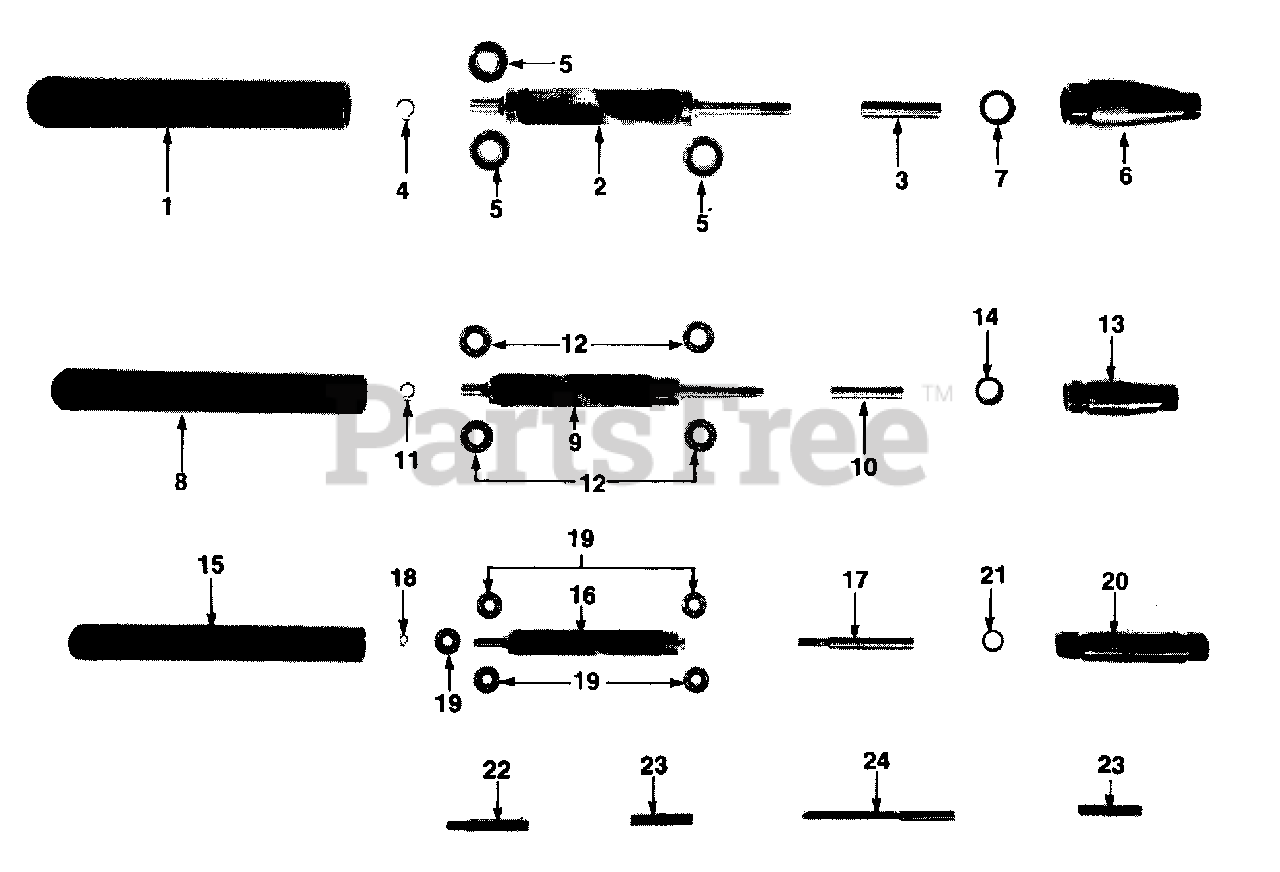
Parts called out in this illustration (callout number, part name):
1	TUBE- w/plug
2	ECCENTRIC WEIGHT
3	DRIVE- Eccentric Weight
4	RING- Snap
5	BEARING- Eccentric Weight (3 required)
6	CONE- Head
7	SEAL- Grease
8	TUBE- w/plug
9	ECCENTRIC WEIGHT
10	DRIVE- Eccentric Weight
11	RING- Snap
12	BEARING- Eccentric Weight (4 required)
13	CONE- Head
14	SEAL- Grease
15	TUBE- w/plug
16	ECCENTRIC WEIGHT
17	DRIVE- Eccentric weight
18	RING- Snap
19	BEARING- Eccentric weight (5 required)
20	CONE- Head
21	SEAL- Grease
22	TIP- Threaded male (Extensions only)
23	TIP- Threaded female (2)
24	TIP- 3 in. hex drive
